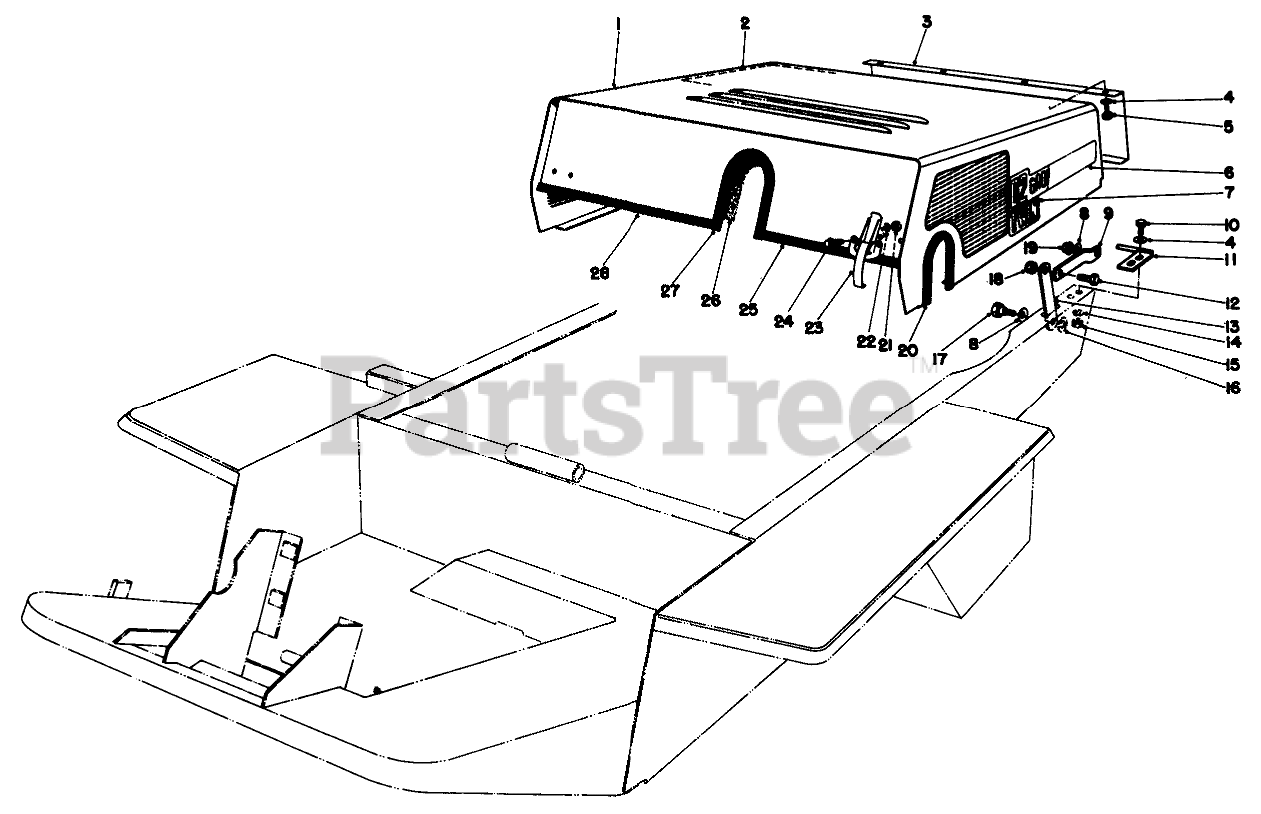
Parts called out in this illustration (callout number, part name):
1	Hood
2	REAR HOOD FOAM STRIP
3	Grille-Rear Panel
4	WASHER-FLAT
5	Screw
6	GM 62 DECAL
7	TWIN DECAL
8	WASHER-SPRING
9	Link Hood
10	SCREW-HH
11	PivotPin L.H.
12	SCREW-HH
13	Tie Hood
14	WASHER-LOCK
15	NUT-HEX
16	WASHER-FLAT
17	SCREW-SHOULDER
18	NUT-HEX
19	NUT-HF
20	HOOD TRIM
21	NUT-HEX
22	WASHER-LOCK
23	CLAMP-SLOTTED
24	SCREW-SHWH
25	HOOD TRIM
26	FRT HOOD FOAM STRIP
27	HOOD TRIM
28	TRIM-HOOD
